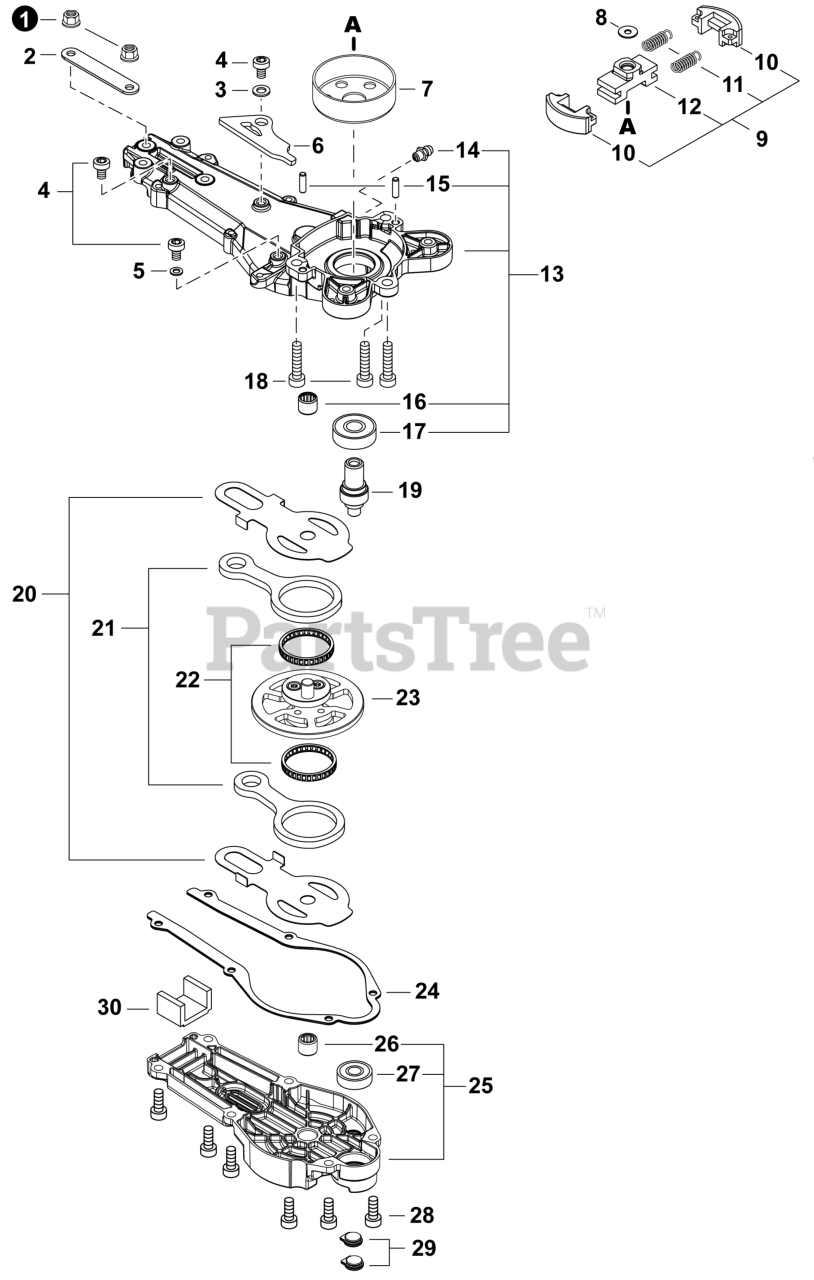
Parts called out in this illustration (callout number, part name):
1	NUT, FLANGE M5
2	PLATE, EYE
3	WASHER 5
4	BOLT, TORX 5x6
5	WASHER 5.5x12x0.8
6	CUSHION
7	DRUM, CLUTCH
8	WASHER 8
9	CLUTCH ASSY
10	SHOE, CLUTCH
11	SPRING, CLUTCH
12	HUB, CLUTCH
13	HOUSING ASSY, GEAR CASE
14	FITTING, GREASE
15	PIN, LOCATING 4x10
16	BEARING, NEEDLE 8
17	BEARING, BALL
18	BOLT, TORX 6x20
19	SHAFT, PINION
20	PLATE, SIDE
22	BEARING, NEEDLE 30
23	GEAR, SPUR
24	GASKET, GEAR CASE
25	COVER ASSY, GEAR CASE
26	BEARING, NEEDLE 8
27	BEARING, BALL 608ZZ
28	BOLT, TORX 5x16
30	PACKING, FELT
